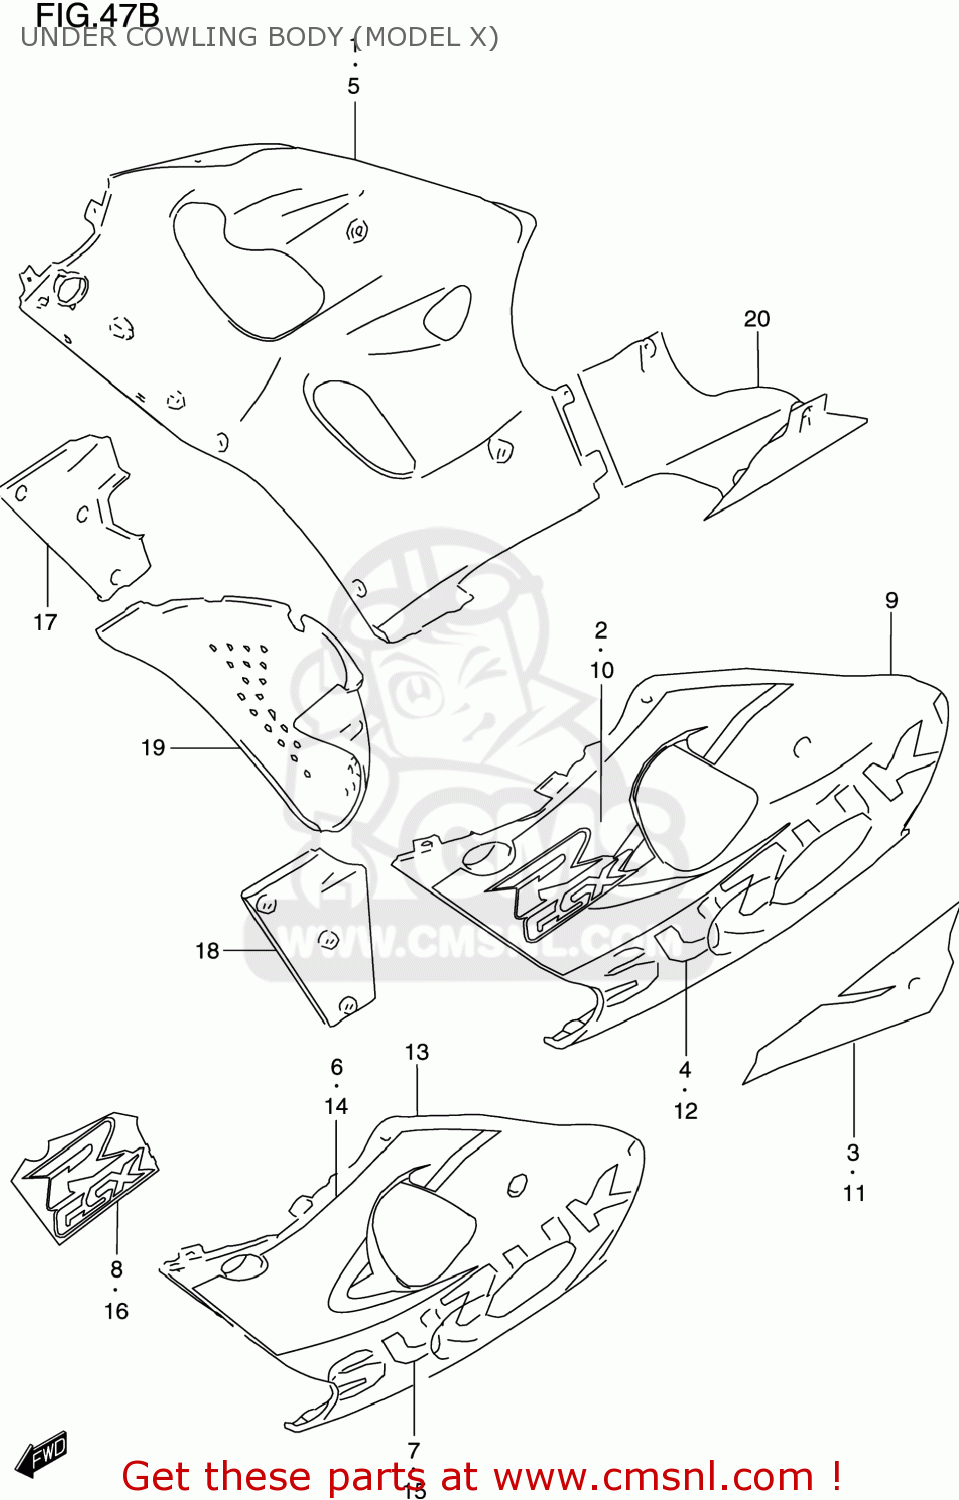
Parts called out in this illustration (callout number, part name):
1	COWLING ASSY,UNDER,R
2	TAPE SET,COWL UNDER,R
3	TAPE,COWL UNDER LWR,R
4	EMBLEM,COWLING UNDER,R
5	COWLING ASSEMBLY,UNDER,RIGHT (Y
6	TAPE SET,COWL UNDER,R
7	EMBLEM,COWLING,UNDER,RIGHT
8	EMBLEM,GSXR,R
9	COWLING ASSEMBLY,UNDER,LEFT
10	TAPE SET,COWL UNDER,L
11	TAPE,COWL UNDER LWR,L
12	EMBLEM,COWLING UNDER,L
13	COWLING ASSEMBLY,UNDER,LEFT (Y
14	TAPE SET,COWL UNDER,L
15	EMBLEM,COWLING UNDER,L
16	EMBLEM,GSXR,L
17	COWLING,UNDER INNER,R
18	COWLING,UNDER INNER,L
19	COWLING,UNDER CTR
20	COWLING ASSY,UNDER RR
